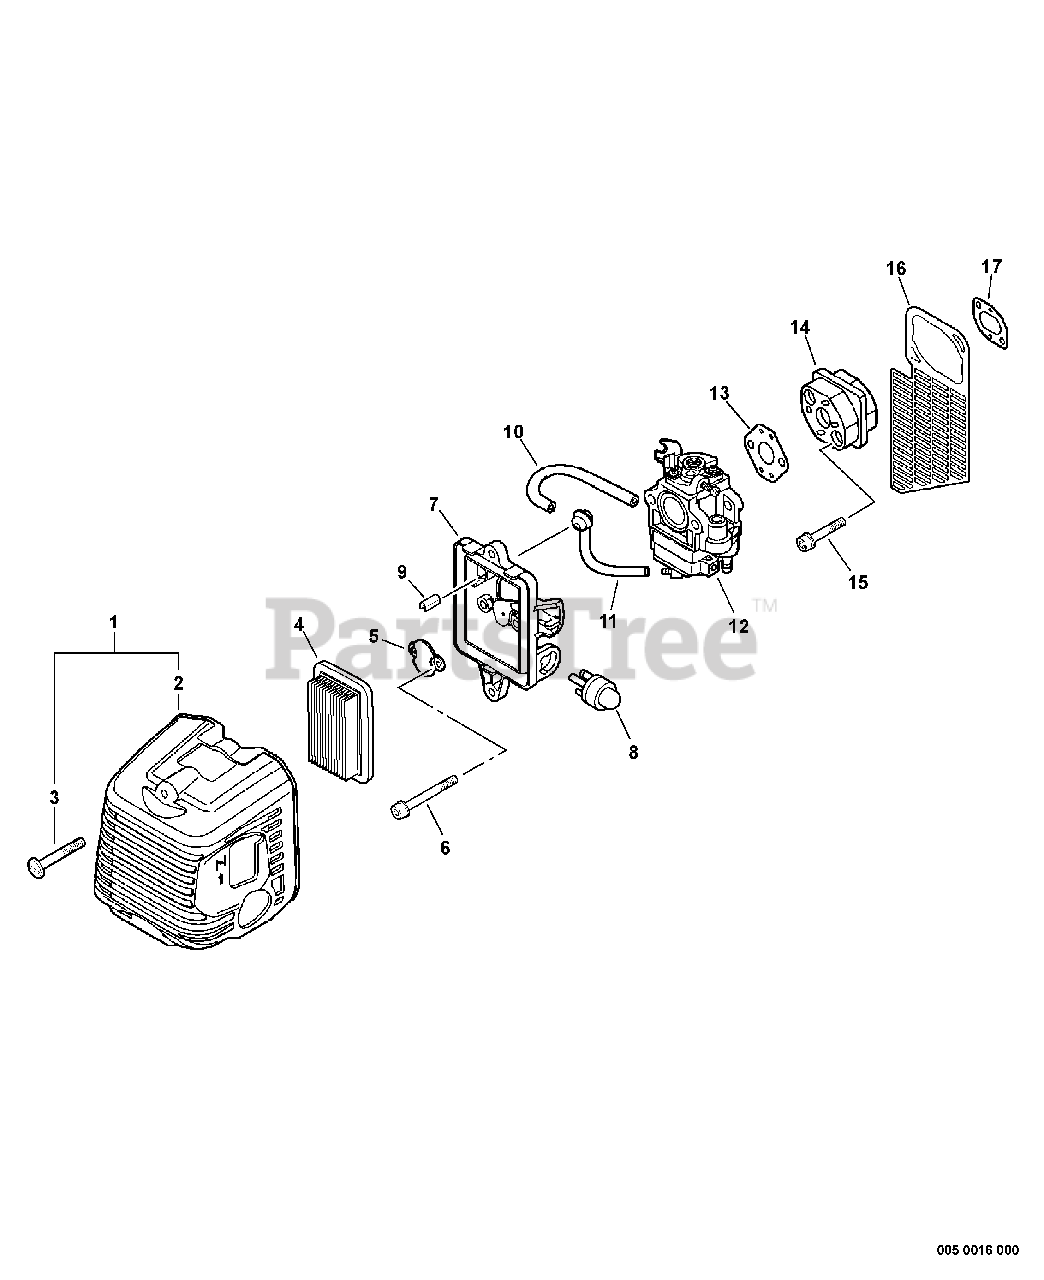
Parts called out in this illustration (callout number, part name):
1	AIR FILTER COVER ASSY
2	COVER, AIR FILTER
3	SCREW - 5X20
4	FILTER, AIR
5	PLATE, PREVENT
6	SCREW - 5X55
7	CASE, AIR FILTER
8	PUMP, PURGE
9	PIPE - INTAKE
10	PIPE - 3X5X80 -- BLACK
11	PIPE - VENT
12	CARBURETOR
13	GASKET, INTAKE
14	INSULATOR, INTAKE
15	SCREW - 5X25
16	GUARD, DEBRIS
17	GASKET, INTAKE
